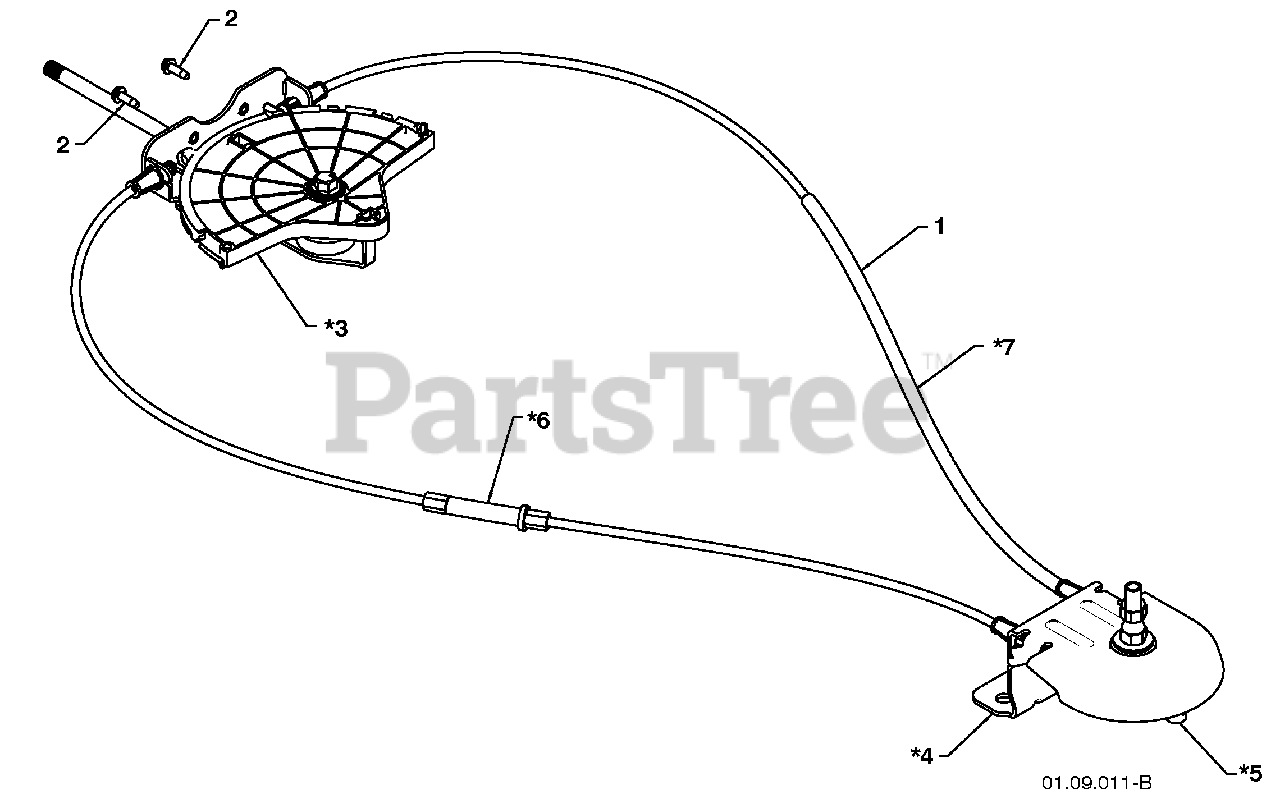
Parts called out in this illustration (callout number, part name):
1	Lever/Cable Rotator Assembly
2	Screw 10-24 X .625
3	Rotator Head
4	Rotator Pivot Bracket
5	Pulley Pivot
6	Cable Assembly Adjustable Gray
7	Cable Assembly Heat Shield Gray
